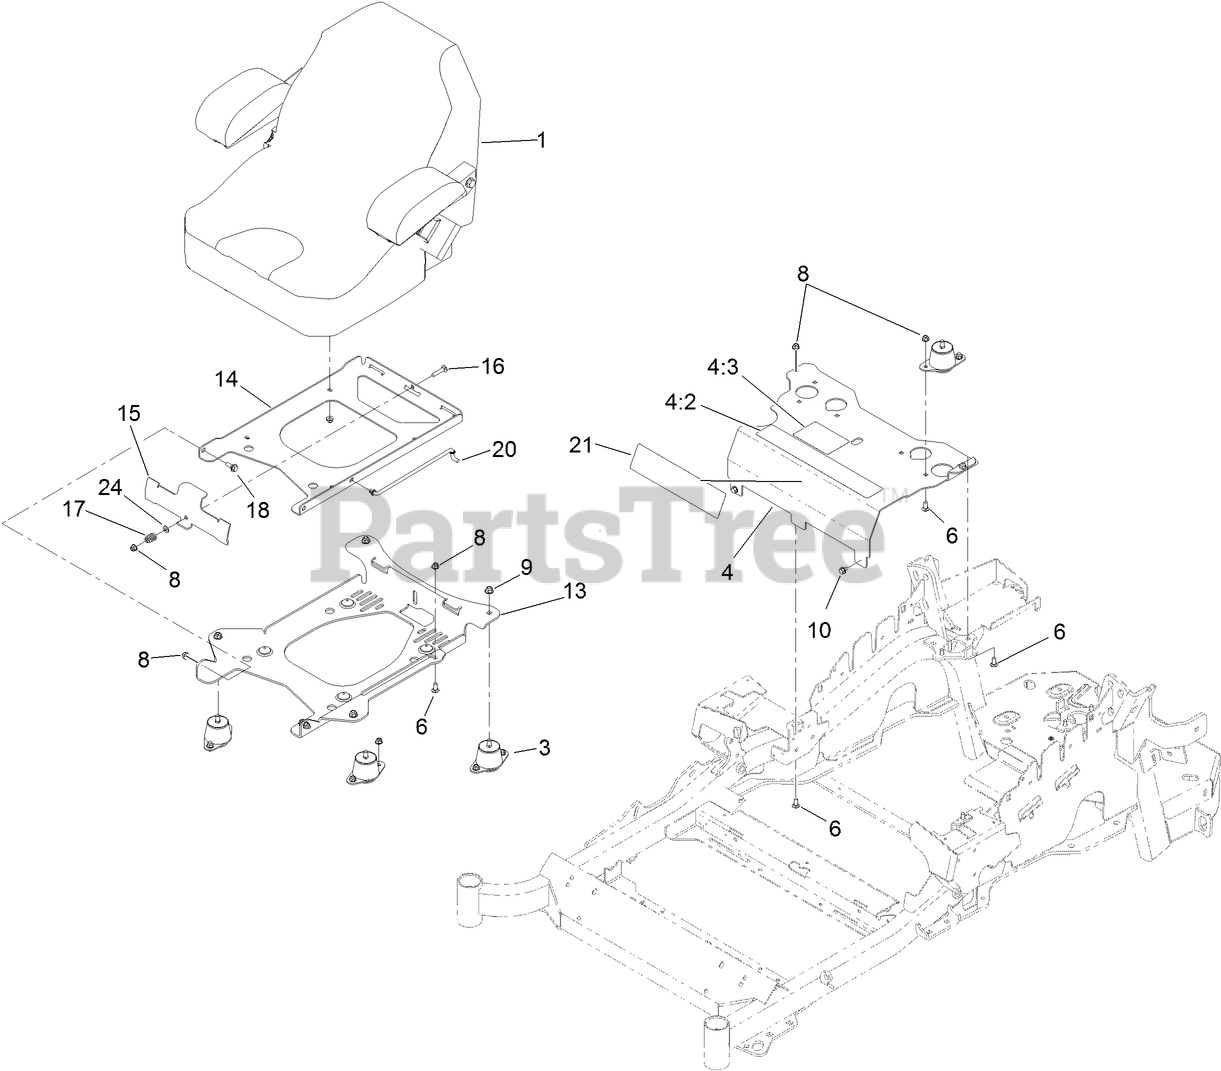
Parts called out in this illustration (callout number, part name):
1	SEAT-STANDARD
3	ISOLATOR-SEAT
4	MOUNT-SEAT
4:2	DECAL-CONSOLE
4:3	DECAL-SERVICE AID
6	SCREW-CARR
8	NUT-HF, NI
9	NUT-HF, NI
10	SCREW
13	PLATE-SUPPORT, SEAT TILT
14	PLATE-FRAME, SEAT TILT
15	PLATE-LATCH, SEAT
16	BOLT-CARR
17	SPRING-COMPRESSION
18	SCREW-SHOULDER
20	ROD-PROP
24	WASHER-PLAIN
